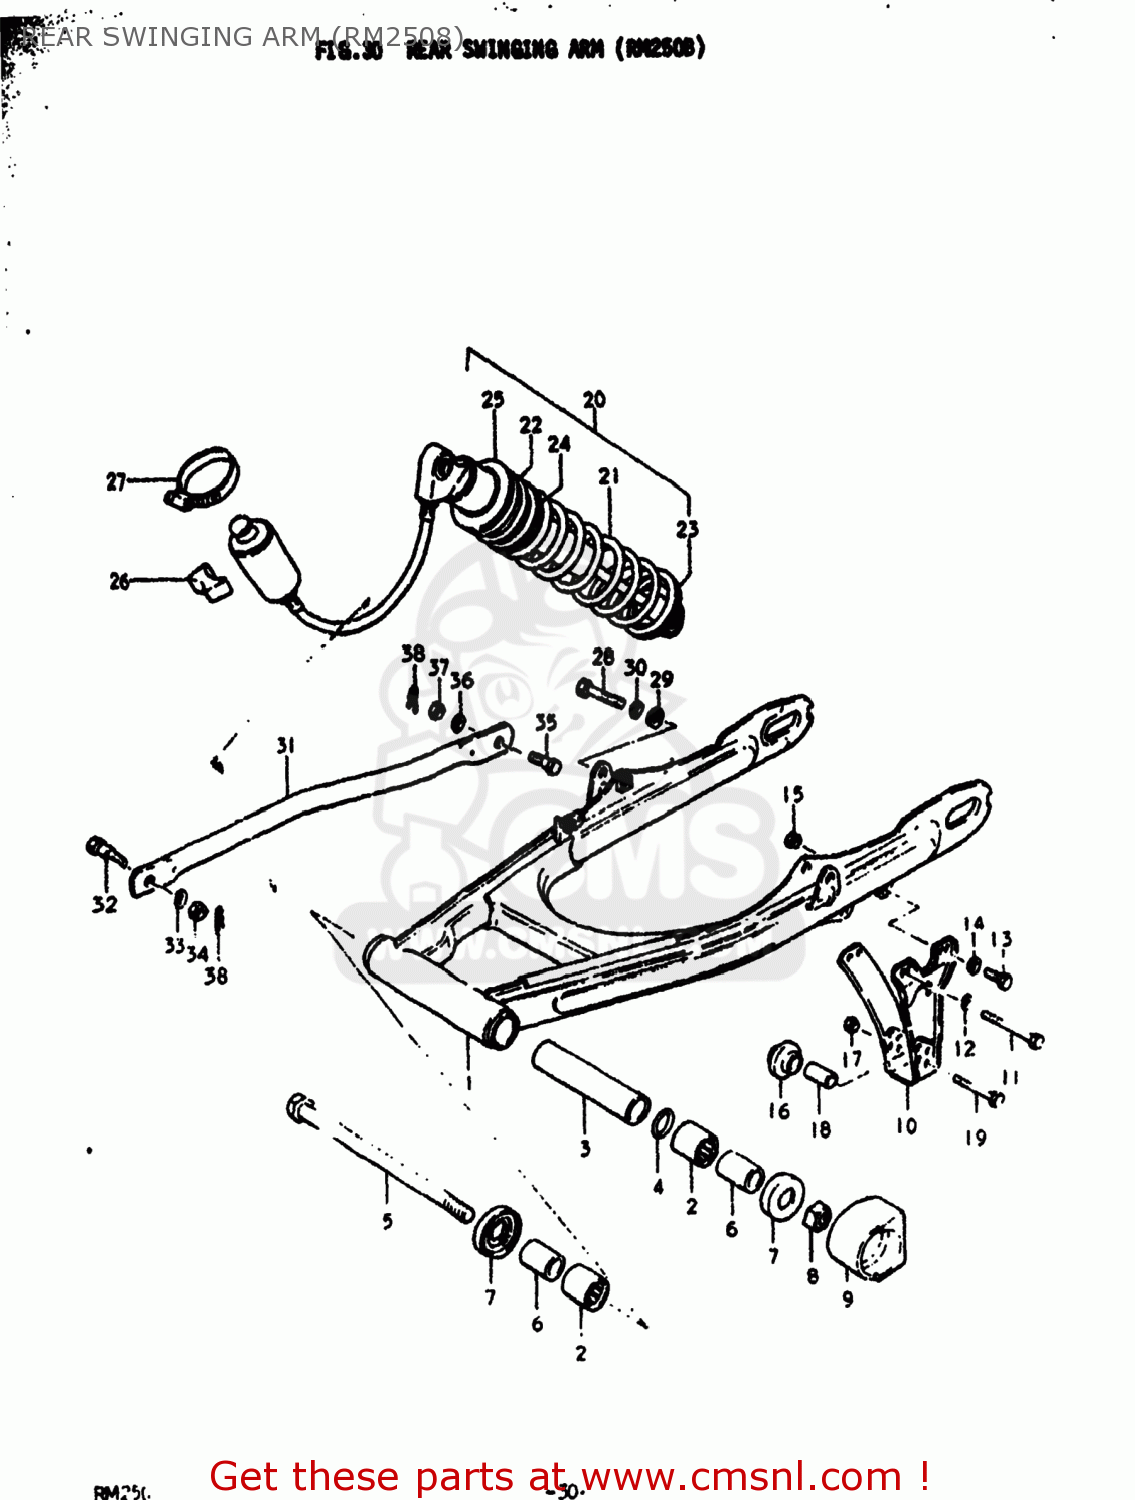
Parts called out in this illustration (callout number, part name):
1	SWING ARM ASSEMBLY,REAR
2	BEARING(20X28X25)
3	SPACER,REAR SWING ARM
4	O RING(D:1.9,ID:18.8)
5	SHAFT,REAR SWING ARM
6	SPACER(14X20X30)
7	THRUST BEARING IKO
8	NUT
9	BUFFER,CHAIN TOUCH DEFLECTOR
10	GUIDE,CHAIN
11	BOLT
12	LOCK WASHER
13	BOLT
14	LOCK WASHER
15	NUT
16	RUBBER,CHAIN GUARD
17	NUT (6MM)
18	SPACER(6.5X10.5X22.5)
19	BOLT
20	ABSORBER ASSEMBLY,REAR SHOCK
21	SPRING
22	SPRING
24	SPRING
25	GUIDE,SPRING
26	CUSHION,RR SHOCK ABSORBER
27	CLAMP
28	BOLT 10X40
29	WASHER
30	LOCK WASHER
31	TORQUE LINK,REAR
32	BOLT(8X22.5)
33	LOCK WASHER
34	NUT
35	BOLT(10X31)
36	LOCK WASHER
37	NUT
38	CLIP
